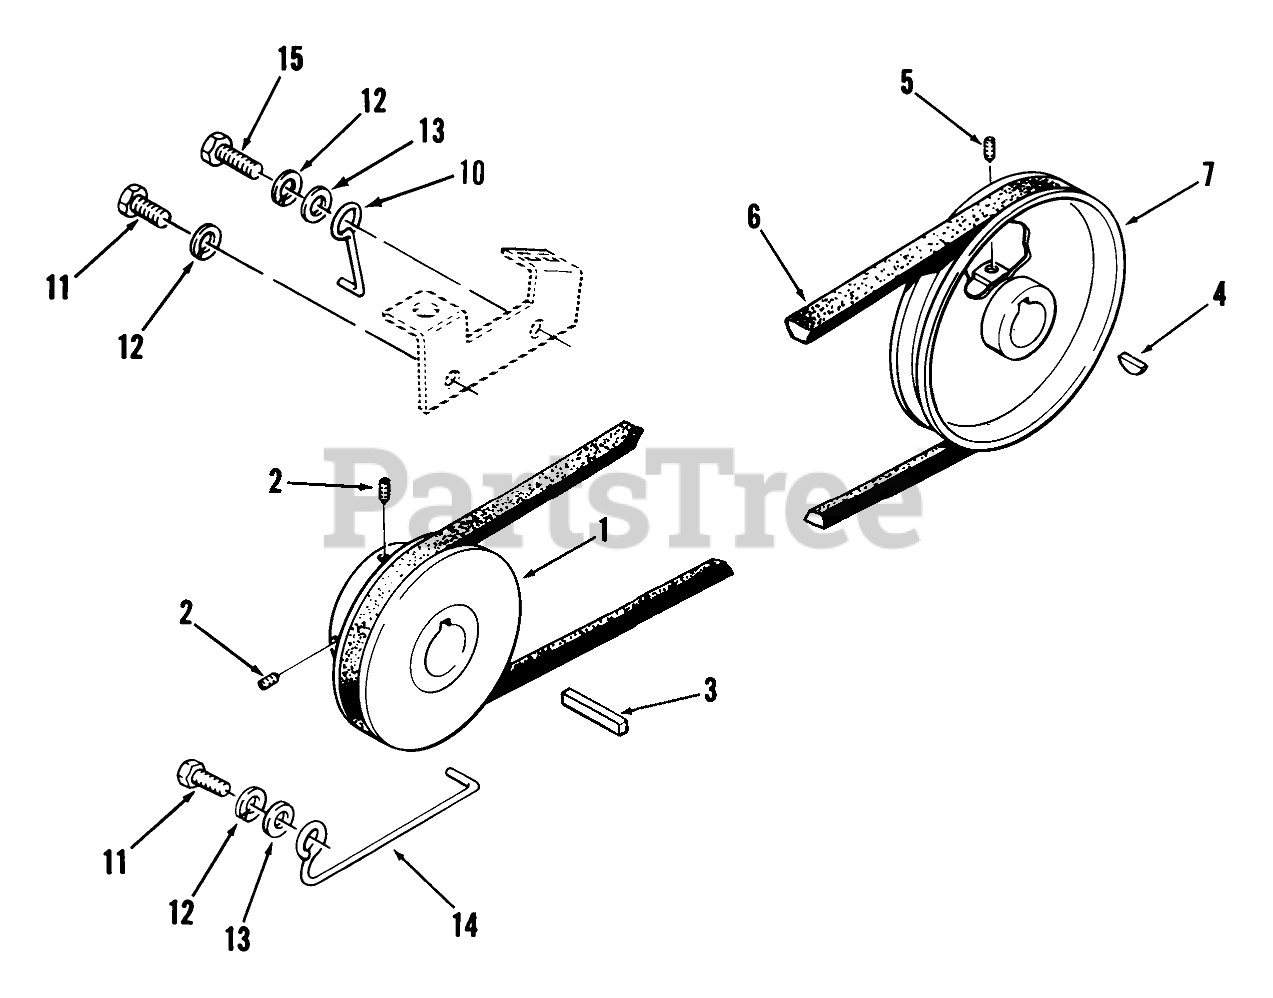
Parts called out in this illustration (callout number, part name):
1	Engine Drive Pulley
1	PULLEY
2	Set Screw
4	KEY-HI PRO
5	Set Screw
6	V BELT
7	PULLEY-TRANSMISSION
10	Belt Guide-Top
11	BOLT
11	7/16-14 x 1 1/4 Bolt
12	LOCKWASHER
13	Washer
13	WASHER
14	Belt Guide-Bottom
14	GUIDE-BELT
15	Bolt
15	7/16-14 x 1 1/4 Bolt
